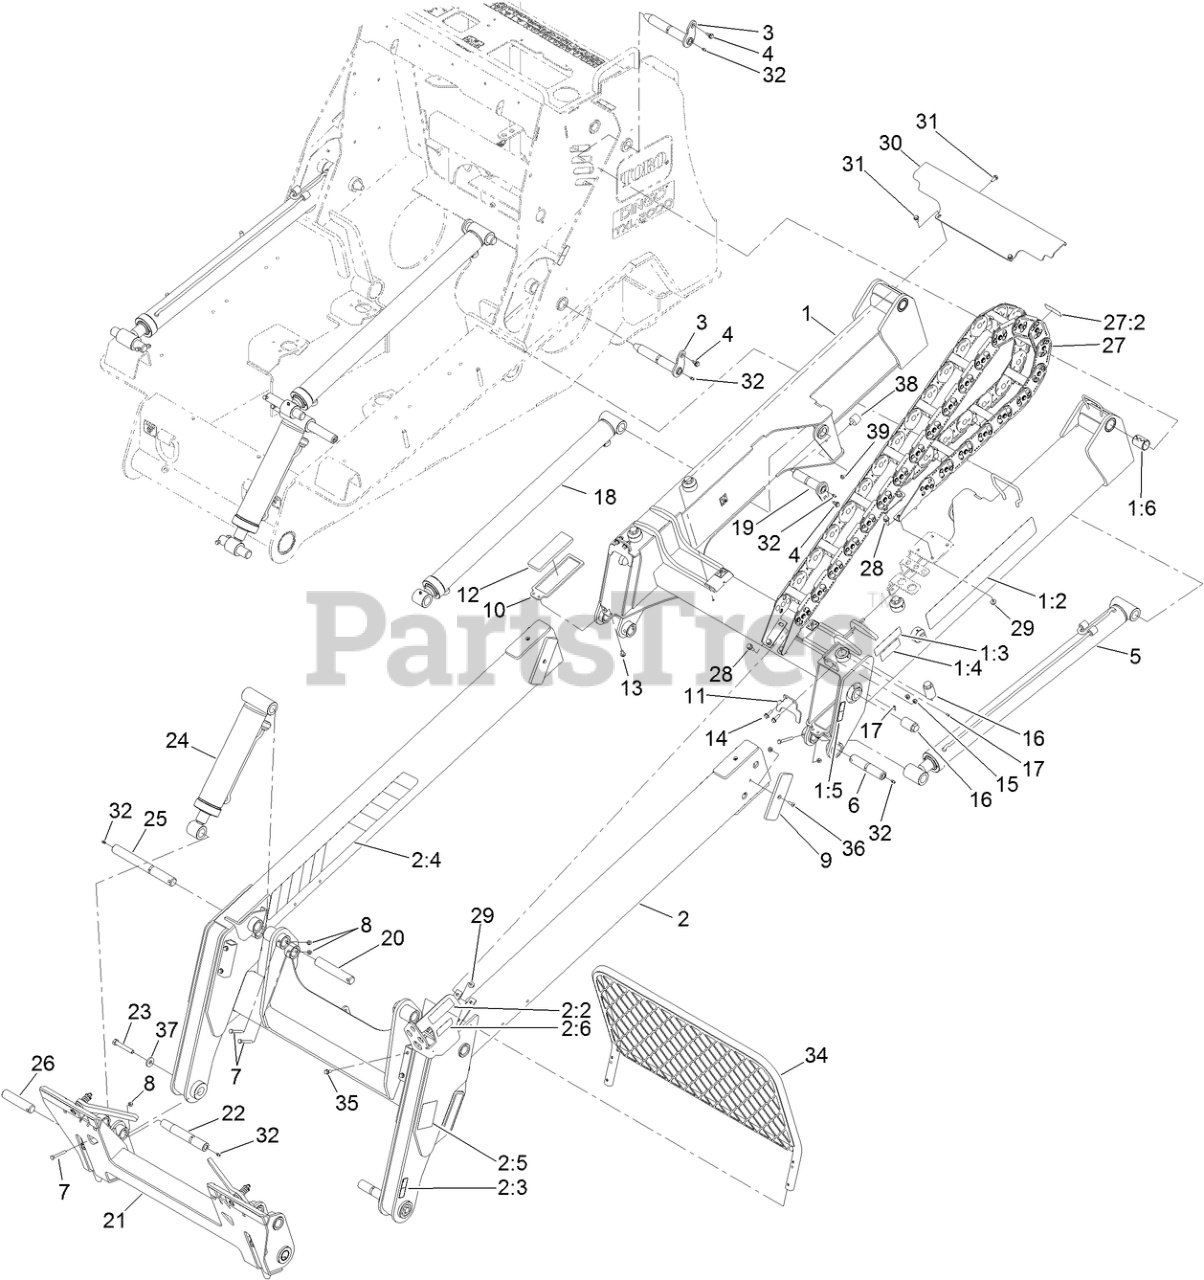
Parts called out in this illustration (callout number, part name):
1	UPPER LOADER ARM ASM
1:2	DECAL-INTELESCOPE
1:3	DECAL-WARNING, CRUSHING
1:4	DECAL-WARNING, BYSTANDERS
1:5	DECAL-WARNING, PINCH POINT
1:6	BUSHING-SPRING
2	LOWER LOADER ARM ASM
2:2	DECAL-CAUTION
2:3	DECAL-WARNING, PINCH POINT
2:4	DECAL-EXTENSION
2:5	DECAL-WARNING, BUCKET
2:6	DECAL-WARNING, HYD PRESSURE
3	PIVOT PIN ASM
4	BOLT-SHOULDER
5	HYD CYL ASM
6	PIN-LINK
7	SCREW-HH
8	NUT-LOCK, NI
9	STRIP-SLIDE, SNAP
10	RETAINER-PAD
11	RETAINER-WEAR,PAD,LEFT
12	STRIP-SLIDE,LOWER
13	SCREW-HWHTF
14	SCREW-HHF
15	NUT-HF, NI
16	SCREW-SLIDE,ADJUSTMENT
17	SCREW-SET, HSH
18	CYL-HYD
19	FLAG PIN ASM
20	PIN-LINK
21	QTACH ASM
22	PIN-LINK, TAPER
23	SCREW-HH
24	HYD CYL ASM
25	PIN-LINK
26	PIN-LINK
27	CARRIER-HOSE
27:2	DECAL-WARNING, PINCH POINT
28	SCREW-HHF
29	NUT-HF, NI
30	PLATE-GUARD
31	SCREW-HWH
32	FITTING-GREASE
34	SCREEN-DEBRIS
35	SCREW-HHF
36	SCREW-HSBH
37	WASHER-FLAT
38	BUMPER-RUBBER
39	NUT-LOCK, NI
